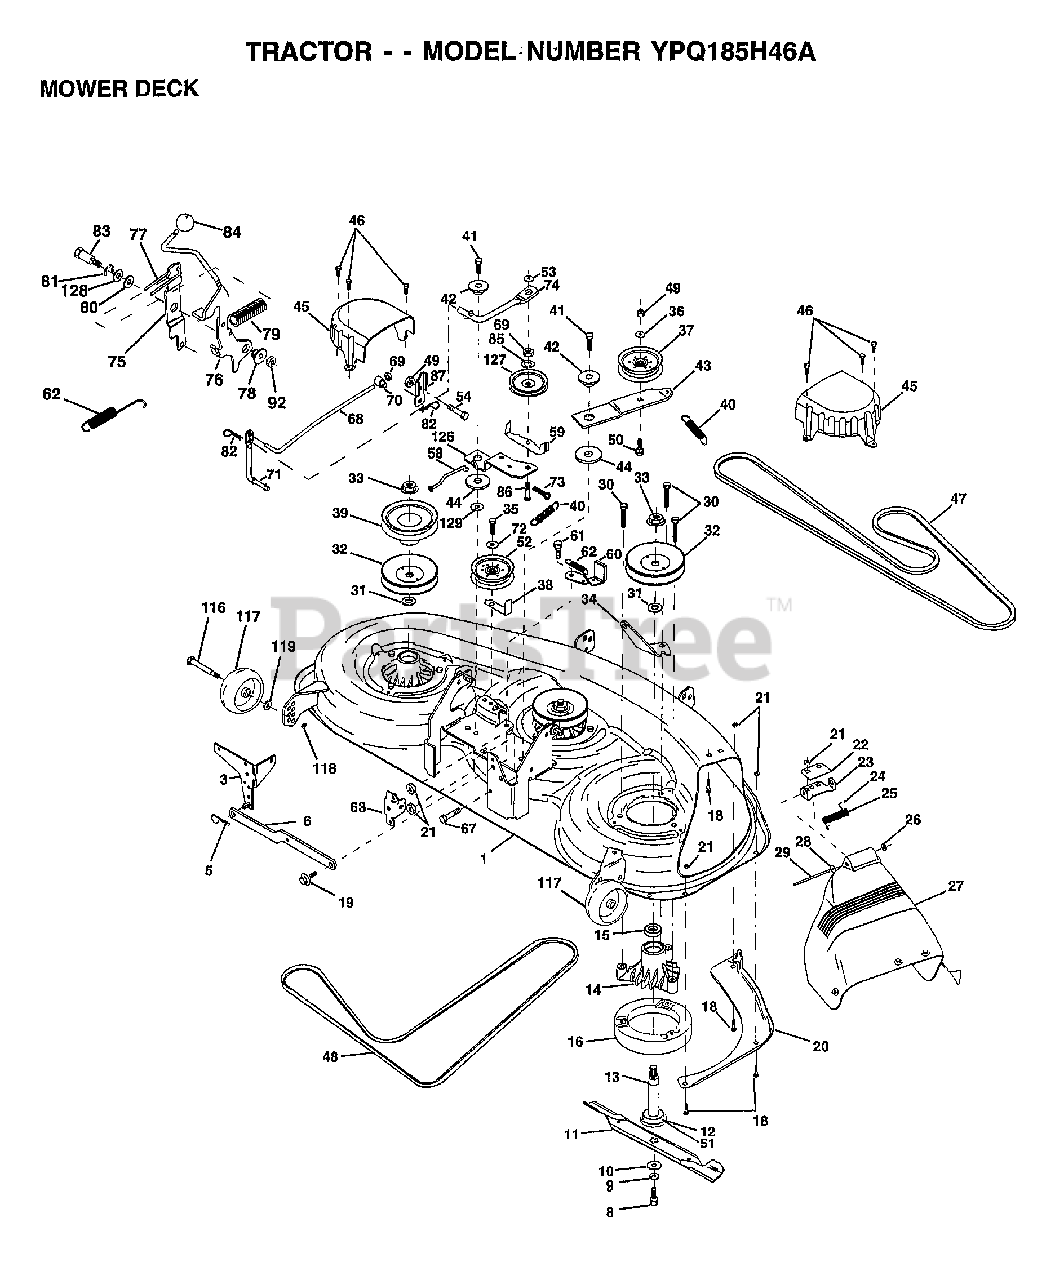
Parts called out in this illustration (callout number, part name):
1	"DECK.ASM.MOWER46"""
3	BRKT.ASM.SW.44/50
8	BLADE BOLT
10	WASHER.HARD.BLADE
11	"BLADE MULCH 46"""
12	BEARING.BALL
13	SHAFT.ASM.W/BRNG
14	HOUSING.MAND.44.V
15	BEARING
16	STRIPPER RND MWR
18	BOLT
19	BOLT SHD 5/16-18
20	BAFFFLE.VORTEX.46
22	STIFFENER BRKT
23	DEFLECTOR BRKT
24	CAP-SLEEVE LT
26	NUT PUSH M
27	SHIELD DEFLECTOR
28	WASHER
29	HINGE ROD
30	"SCREW-THD ROLL,WA"
31	WASHER
32	PULLEY.MAND.36/46
34	ANCHOR.SPRING.46
35	SCREW LT
36	WASHER
37	FLAT IDLER PULLEY
38	"KEEPER BELT,IDLER"
39	PULLEY.DRV.DCK.46
40	"SPRING.SEC.44""VEN"
41	SCREW
42	SPACER.RETAINER.MOWER
43	ARM.IDLER.DECK.46
44	HARDENED WASHER
45	COVER.MANDREL.46
46	SCREW.1/4-20X5/8
47	BELT-V.SEC.46.KEL
48	V BELT MOWER
50	BOLT.3/8-16X1.50
51	WASHER.FELT.
52	"PULLEY IDLER,FLAT"
53	WASHER
54	BOLT
58	"LINK BRAKE, 43"""
59	"GUIDE BELT,46""MOW"
60	ARM ASM BRAKE
61	BOLT.SHOULDER.5/16-18
62	RETURN SPRING
63	"BRKT ROD,CLUTCH"
67	BOLT
69	NUT
70	TRUNION ADJ
71	PIVOT ROD
72	WASHER
73	COTTER PIN
74	LINK CLUTCH
75	CLUTCH ARM SECOND
76	LEVER.ASM.CLUTCH
77	SPRING KEEPER
78	BUSHING
79	SPRING.CLUTCH.MWR
80	WASHER
81	RING
82	RETAINER M
83	SHOULDER BOLT
84	KNOB.RD.7/16-14
85	LOCKWASHER
86	"BOLT CARR, SH"
87	BRACKET.EXTENSION
92	NUT
116	BOLT.SHOULDER
117	WHEEL GAGE DONUT
118	LOCKNUT
119	WASHER
127	PULLEY.IDLER.4.25
128	WASHER .T
129	WASHER T
